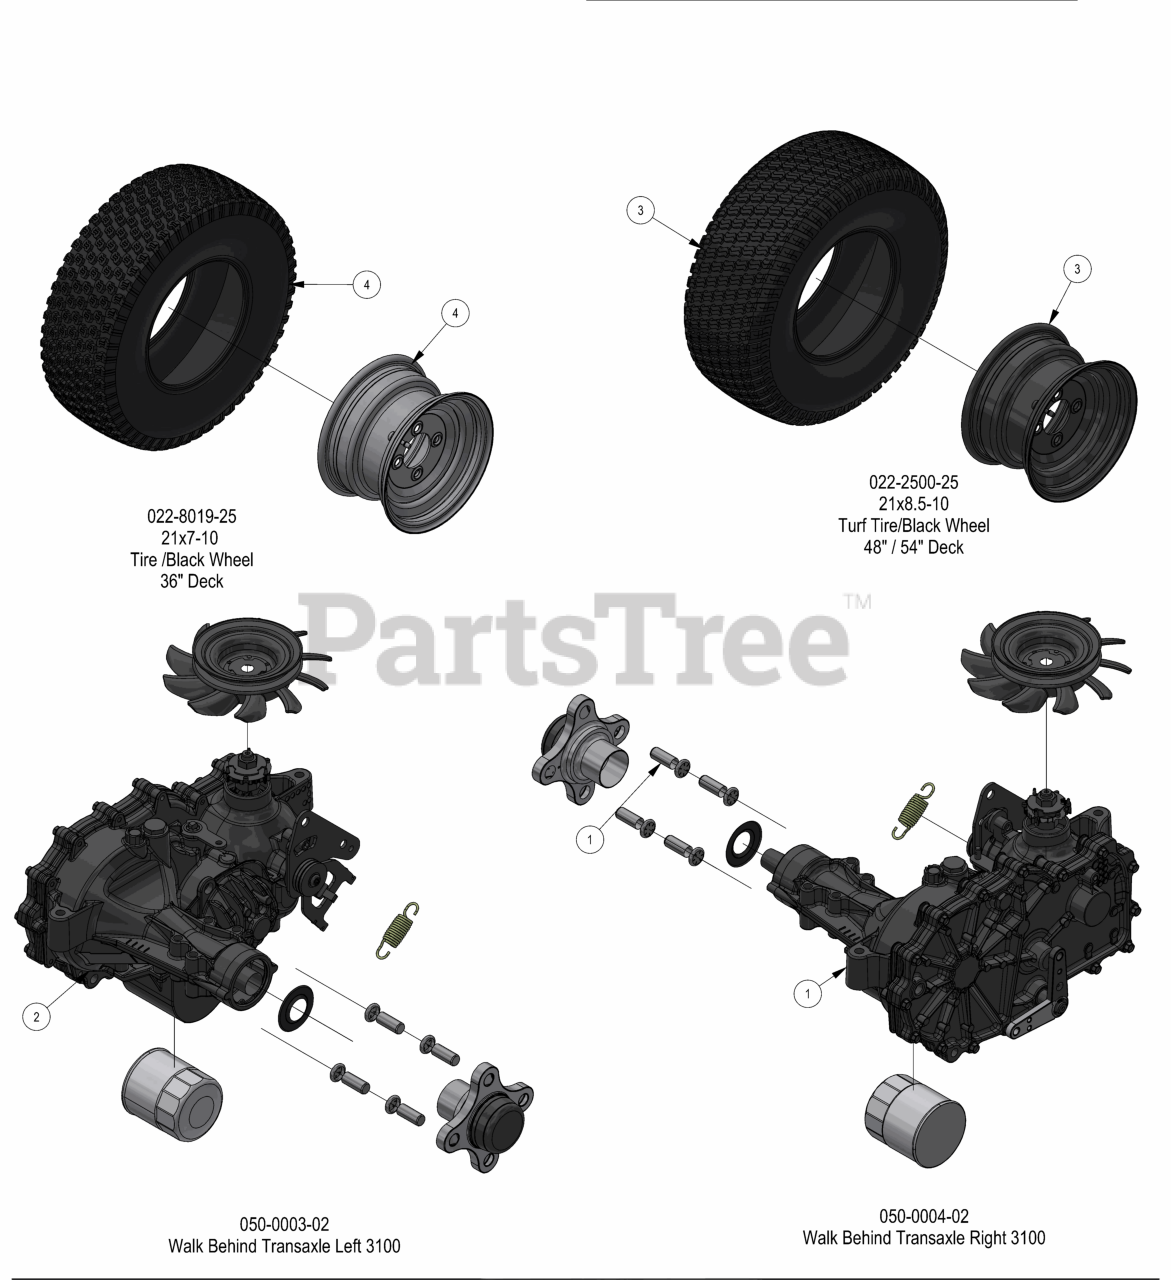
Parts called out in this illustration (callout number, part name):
1	Walk Behind Transaxle Right 3100
2	Walk Behind Transaxle Left 3100
3	Reaper Tire Assembly (21 x 8.5 - 10)
4	Reaper Tire Assembly (21x7-10)
